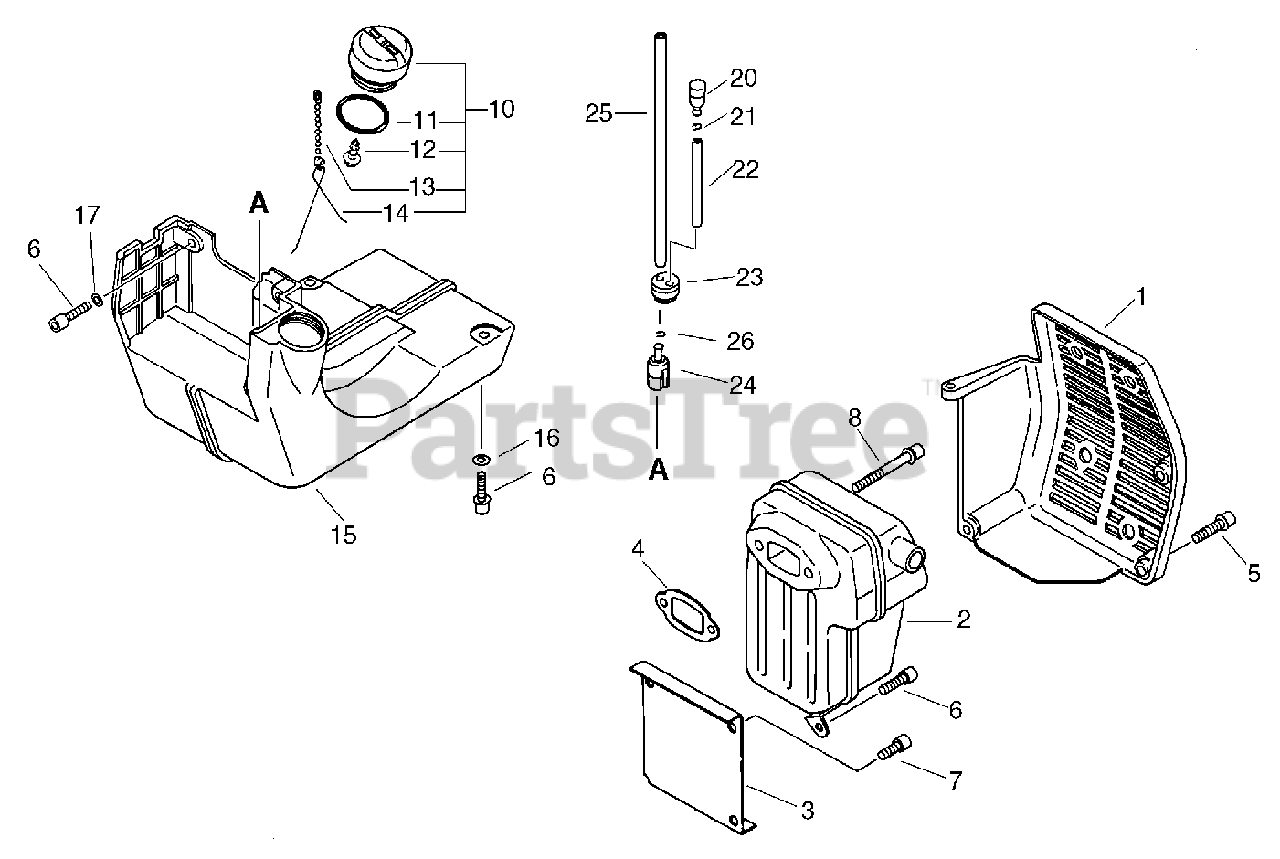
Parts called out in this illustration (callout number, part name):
1	COVER, EXHAUST
2	MUFFLER
3	SHIELD, EXHAUST
4	GASKET, EXHAUST
5	SCREW - 5X18
6	SCREW - 5X16
7	SCREW - 5X10
8	SCREW - 5X75
10	CAP ASSY
11	O-RING - 32
12	SCREW - 3X8
13	CONNECTOR, CAP
14	RETAINER
15	TANK, FUEL
17	WASHER - 5
20	VENT, FUEL TANK
21	CLIP - 6
22	PIPE - FUEL
23	GROMMET
24	FILTER, FUEL
25	PIPE - FUEL
26	CLIP - 6.5
